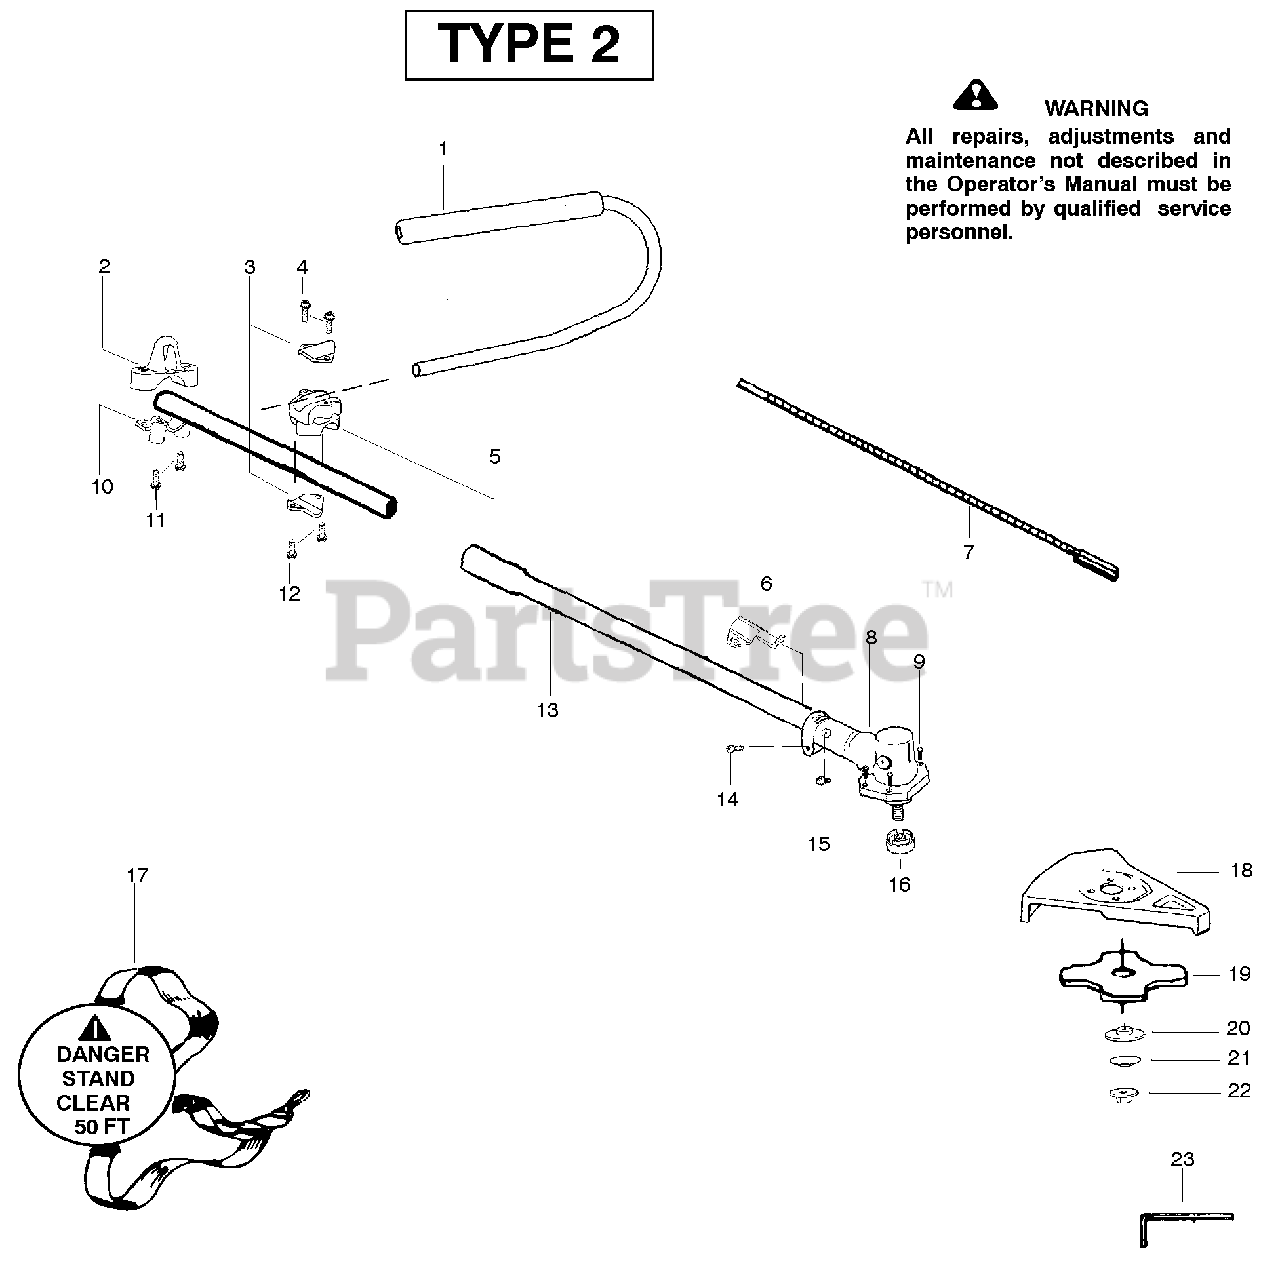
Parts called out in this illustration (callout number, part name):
1	Kit-Handlebar
2	Clamp-Harness Upper
3	Clamp-Bracket
5	Clamp-Handlebar, (7/8")
5	Clamp-Handlebar, (1")
6	Bracket-Shield
7	Flexshaft-Split boom
8	Assy-Gearbox
10	Clamp-Harness Lower
13	Assy.-Driveshaft
15	Screw-Alignment
16	Dust cup - Blade
17	Assy-Shoulder Strap
18	Kit-Blade Shield
19	Accy.-Weed Blade (8")
20	Washer-Blade Retaining
21	Washer-Belleville
22	Nut-Flange
23	Wrench-Hex (5/32")
